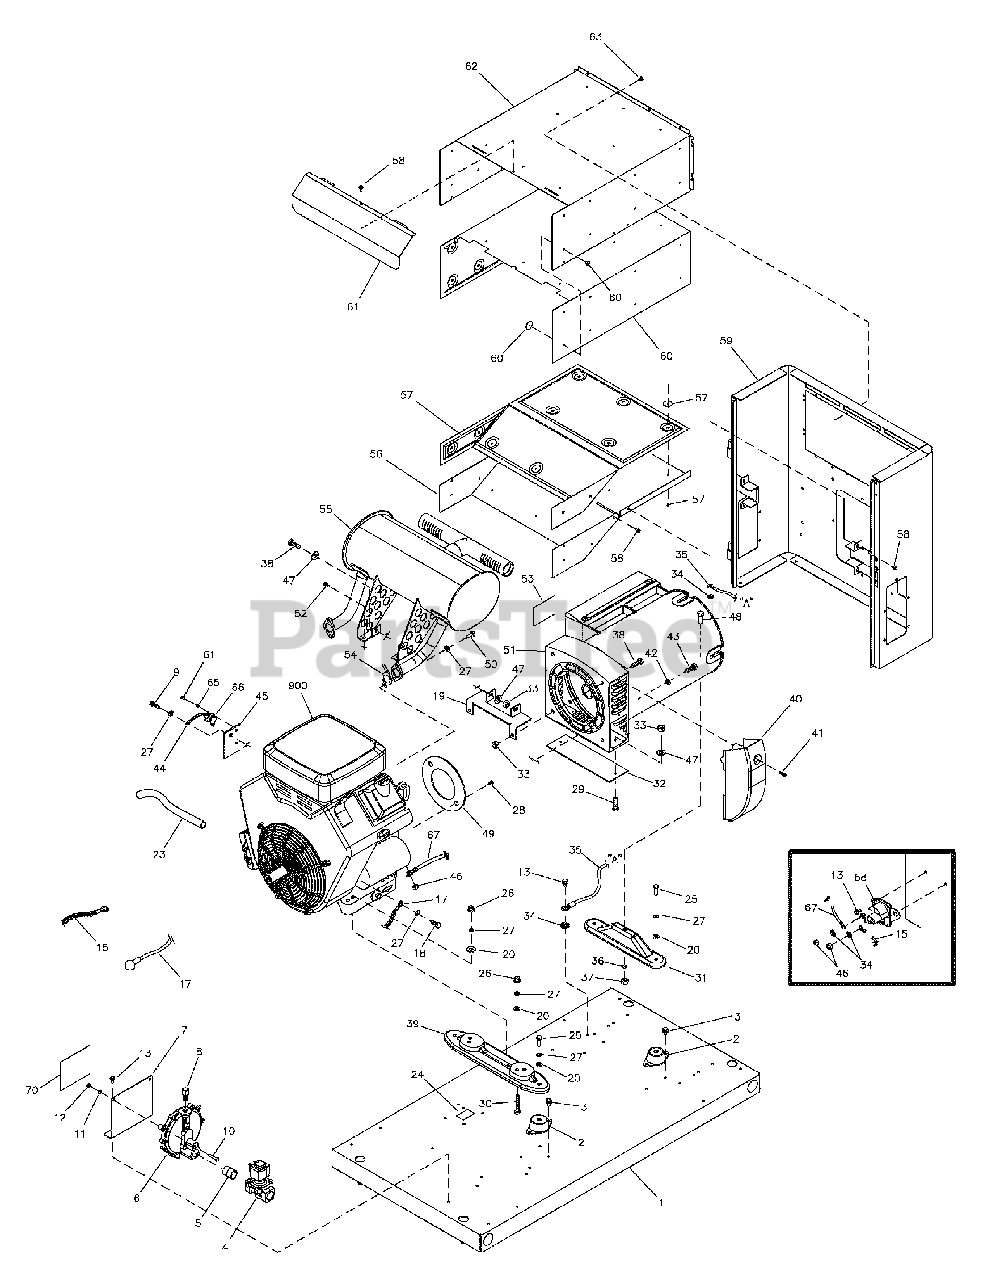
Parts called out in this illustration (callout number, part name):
2	MOUNT, Vibration
4	SOLENOID, Gas Fuel
6	REGULATOR, NG/LPG
7	BRACKET
9	* CAPSCREW, Hex, Head, M8-1.25 x 12
10	* CAPSCREW, Hex, Head, M6-1 x 30
11	* WASHER, Lock, 1/4
12	* NUT, M6-1
13	BOLT
18	* CAPSCREW, Hex, Head, M8-1.25 x 16
20	* WASHER, Flat, 5/16-M8
23	HOSE, Oil Drain
24	DECAL
25	* CAPSCREW, Hex, Head, 5/16-18 x 1
26	* NUT, 5/16-18
27	* WASHER, Lock, 5/16-M8
28	* CAPSCREW, Hex, Head, 5/16-24 x 3/4
29	* CAPSCREW, Hex, Head, 1/4-20 x 1
30	* CAPSCREW, Hex, Head, 5/16-18 x 1-3/4
31	SUPPORT, Alternator
34	* WASHER, Shakeproof, M6-1/4
36	* WASHER, Lock, M10
37	* NUT, Hex, M10
38	* CAPSCREW, Hex, Head, 1/4-20 x 3/4
39	SUPPORT, Alternator
42	* WASHER, Lock, 3/8
43	* CAPSCREW, Hex, Head, 3/8-16 x 1-1/4
45	PLATE, Temp Switch
46	* NUT, Hex, 14-20
47	* WASHER, Flat, M6
48	* CAPSCREW, Hex, Head, M10-1.5 x 30
51	ALTERNATOR, Complete
53	DECAL
59	BULKHEAD, Alternator
62	BOX, Muffler Top
64	* SCREW, Phillips Head, 4-40 x 0.19
65	* WASHER, Lock, #4
66	SWITCH, Temp
68	SOLENOID, Starter
900	** ENGINE
